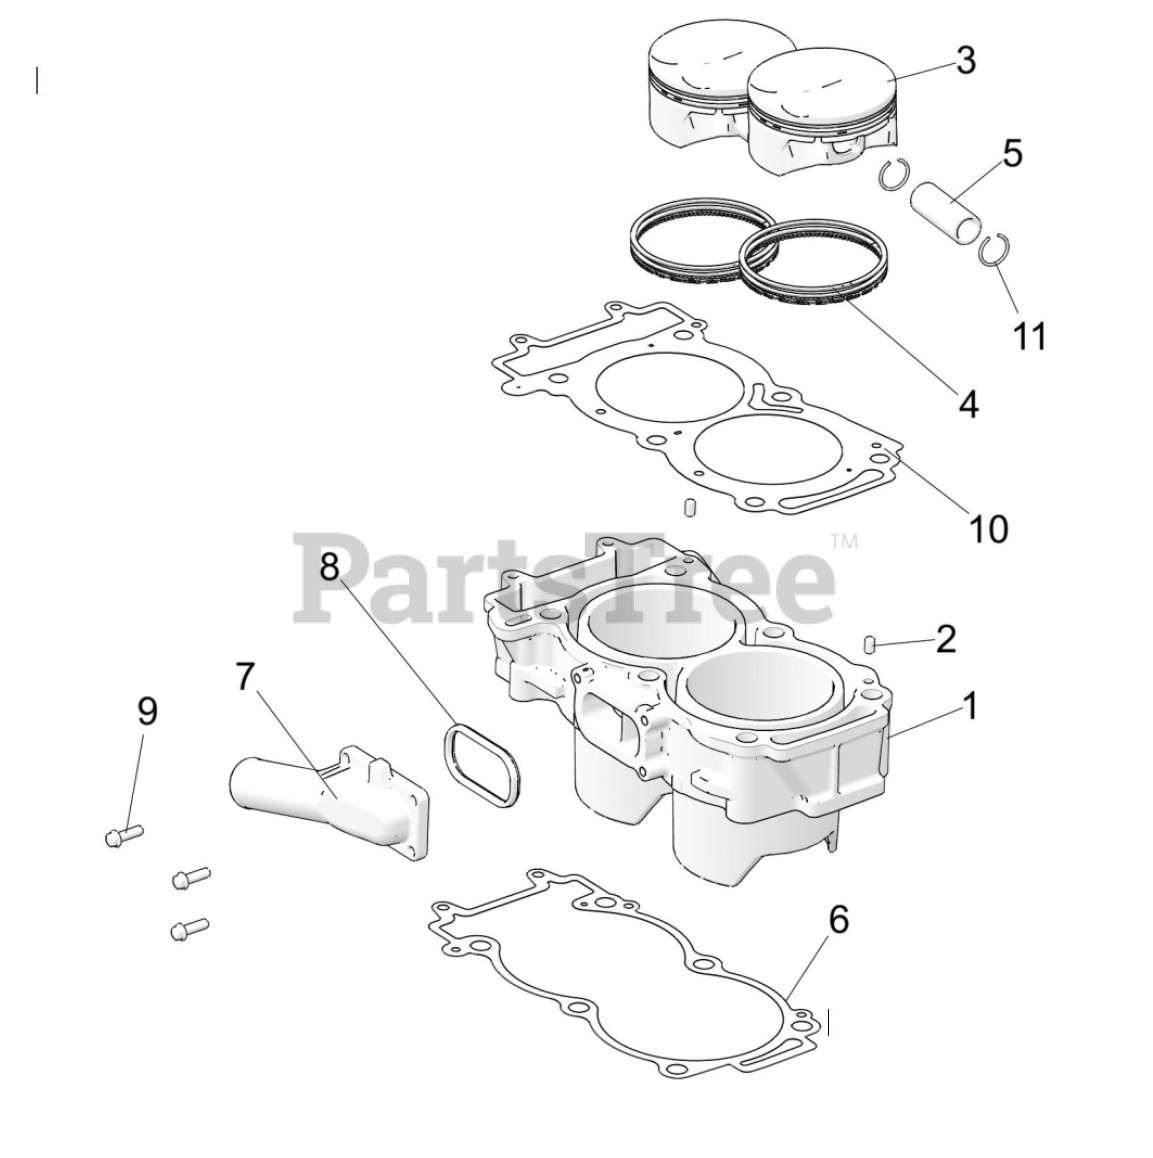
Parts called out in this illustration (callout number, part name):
1	ASM-CYLINDER,875
2	PIN-DOWEL,M6X10
3	ASM-PISTON
4	KIT, PISTON RINGS
5	PIN, PISTON
6	GASKET, BASE, 2 CYL
7	COVER, WATER INLET, CAST
8	GASKET, WATER, INLET
9	SCR-M6X20,HXFLG,0600214
10	GASKET-CYLINDER,HEAD
11	RING-RTG,ROUND,20.0X1.6
